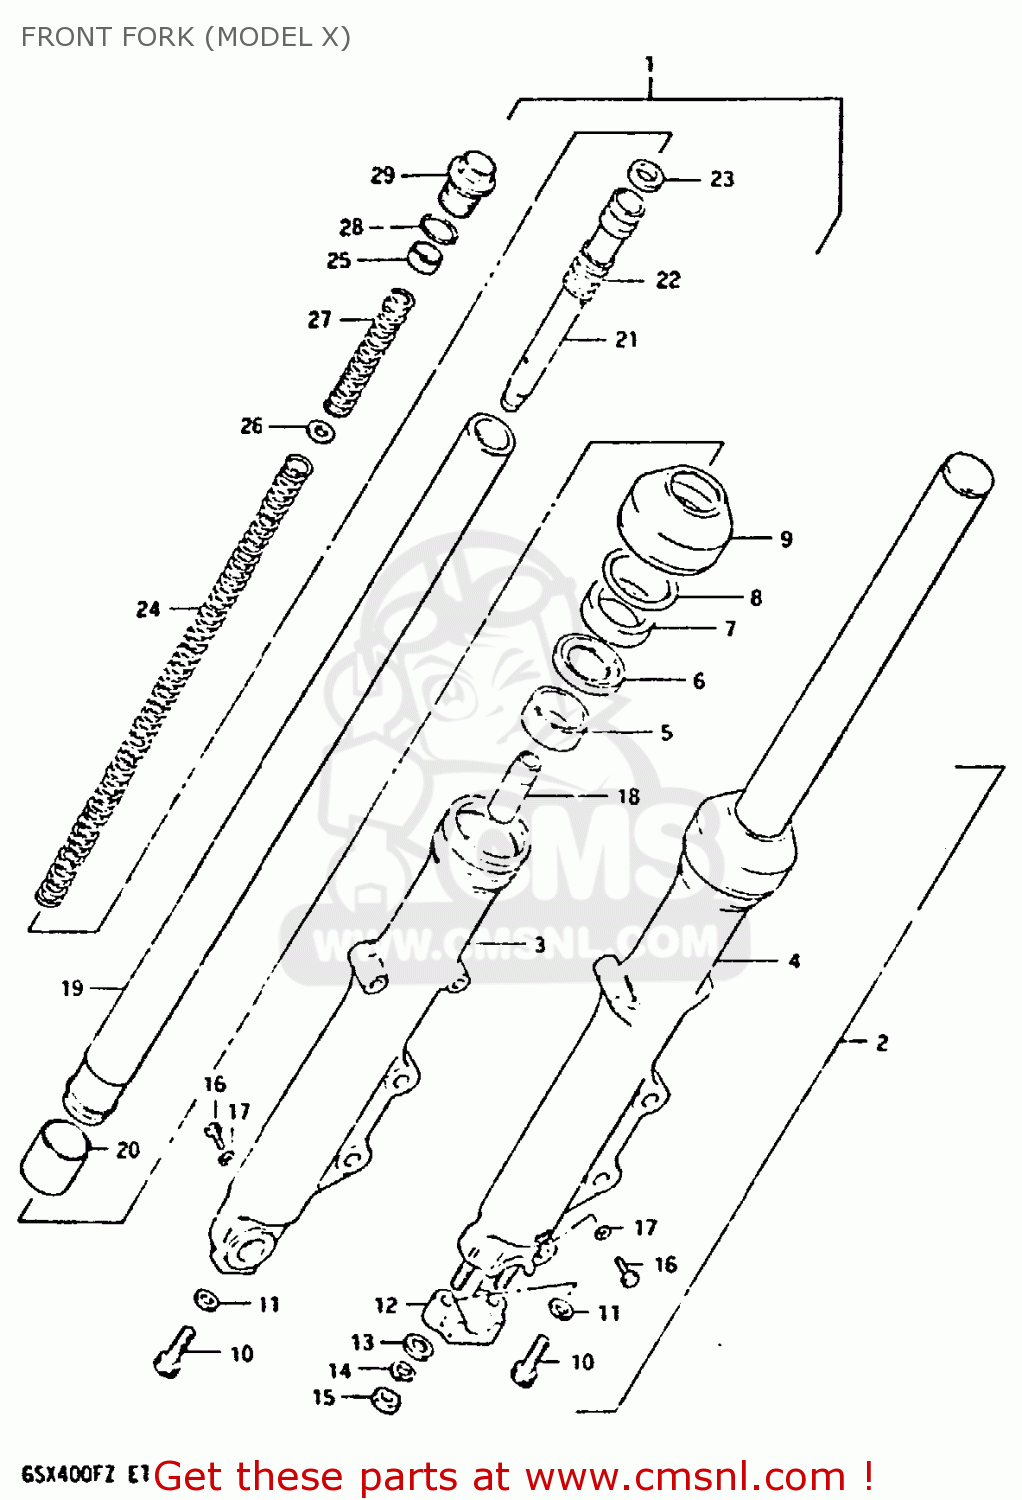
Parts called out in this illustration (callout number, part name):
1	DAMPER ASSY, RH
2	DAMPER ASSY, LH
3	OUTER TUBE RH
4	OUTER TUBE LH
5	BUSH,GUIDE
6	SPACER,OIL SEAL
7	OIL SEAL,FRONT FORK
8	CIRCLIP,FORK OIL SEAL
9	DUST SEAL
10	BOLT(8X27)
11	GASKET (NAS)
12	HOLDER,AXLE
13	WASHER
14	LOCK WASHER
15	NUT
16	BOLT(6X8)
17	GASKET,DRAIN,PLUG (NAS)
18	PIECE,OIL LOCK
19	INNER TUBE
20	BUSH
21	CYLINDER
22	SPRING,REBOUND
23	RING,PISTON
24	SPRING B
25	SPACER,FRONT FORK SPRING
26	SEAT,SPRING
27	SPRING A
28	O RING
29	BOLT
